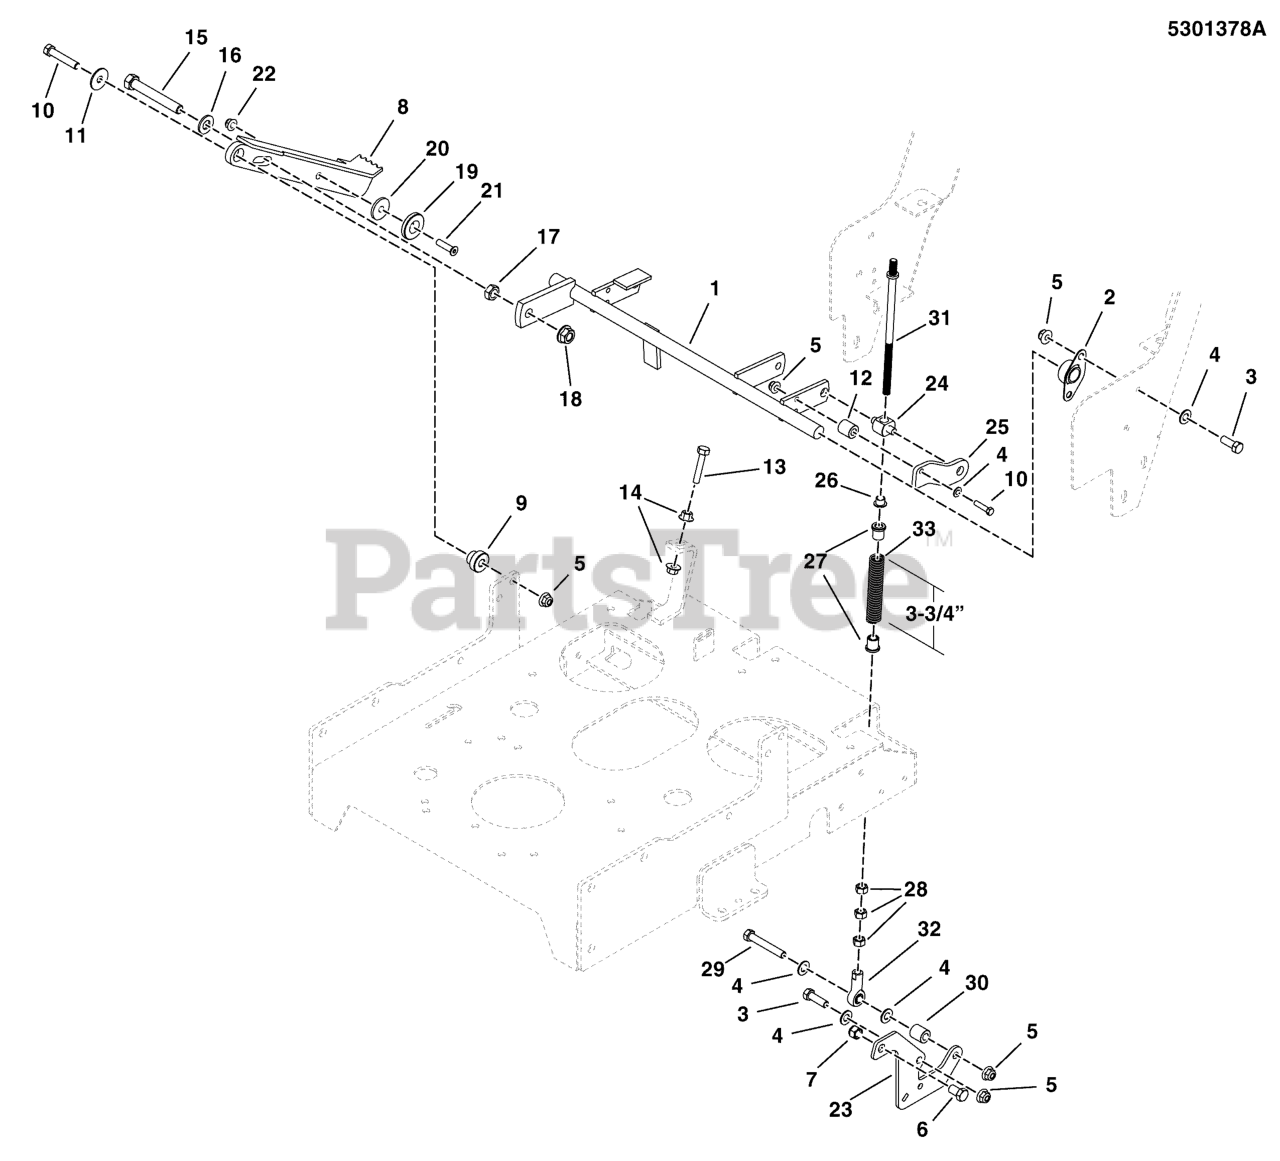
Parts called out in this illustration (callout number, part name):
1	WELD, CONTROL SHAFT, SW20 - RED
2	BEARING, BRONZE FLANGE, 3/4"
3	BOLT, 3/8-16 X 1" GD5 CZ
4	WASHER, 3/8 SAE
5	NUT, 3/8 - 16 HEX NYLOCK FLANGE
6	BOLT, 7/16-14 X 3/4, GD 5 YZ
7	NUT, 7/16-14 HEX TOP LOCK
8	WELD, FOOT PEDAL, SW30 - RED
9	SPACER, .38 X 1.13 X .781 STEP, CZ
10	BOLT, 3/8-16 X 2, GD5, CZ
11	WASHER, .390 X 1.50 X .109, YZ
12	SPACER, .39 X 1.00 X .88, CZ
13	BOLT, 5/16-24 X 1-3/4, FULL THRD, GD5 YZ
14	NUT, .31-24 HEX FLG SERRATED LK
15	BOLT, 1/2-13 X 3-1/2, HEX HD, GD5, CZ (SV)
16	WASHER, 1/2 SAE
17	NUT, Hex, Jam, 1/2-13
18	NUT, Hex Flange, Nylock, 1/2-13
19	SPACER, .34 X 1.54 X .25 - UHMW
20	WASHER, .34 X 1.25 X 10 GA
21	SCREW, 5/16-18 X 1-1/4, FSHS, BLK, ALLEN
22	NUT, 5/16-18 HEX NYLOCK FLANGE NUT
23	PLATE, CONTROL ARM, SW20 - RED
24	TRUNION, 1/2" POSTS, STAINLESS
25	BRACKET, PIVOT SUPPORT - RED
26	BUSHING, .38ID X .47 OD X .38L, FL
27	BUSHING, .38 X .75 X .75, PLASTIC
28	NUT, 3/8-24 HEX (SV)
29	BOLT, 3/8-16 X 2-1/2" GD5 CZ
30	SPACER, .38 X .75 X 1.06, YZ
31	ROD, RETURN CONTROL, SW30
32	BALL JOINT, 3/8-24 FEMALE
33	SPRING-COMP, .615ID X 4.00LG X .080WR
